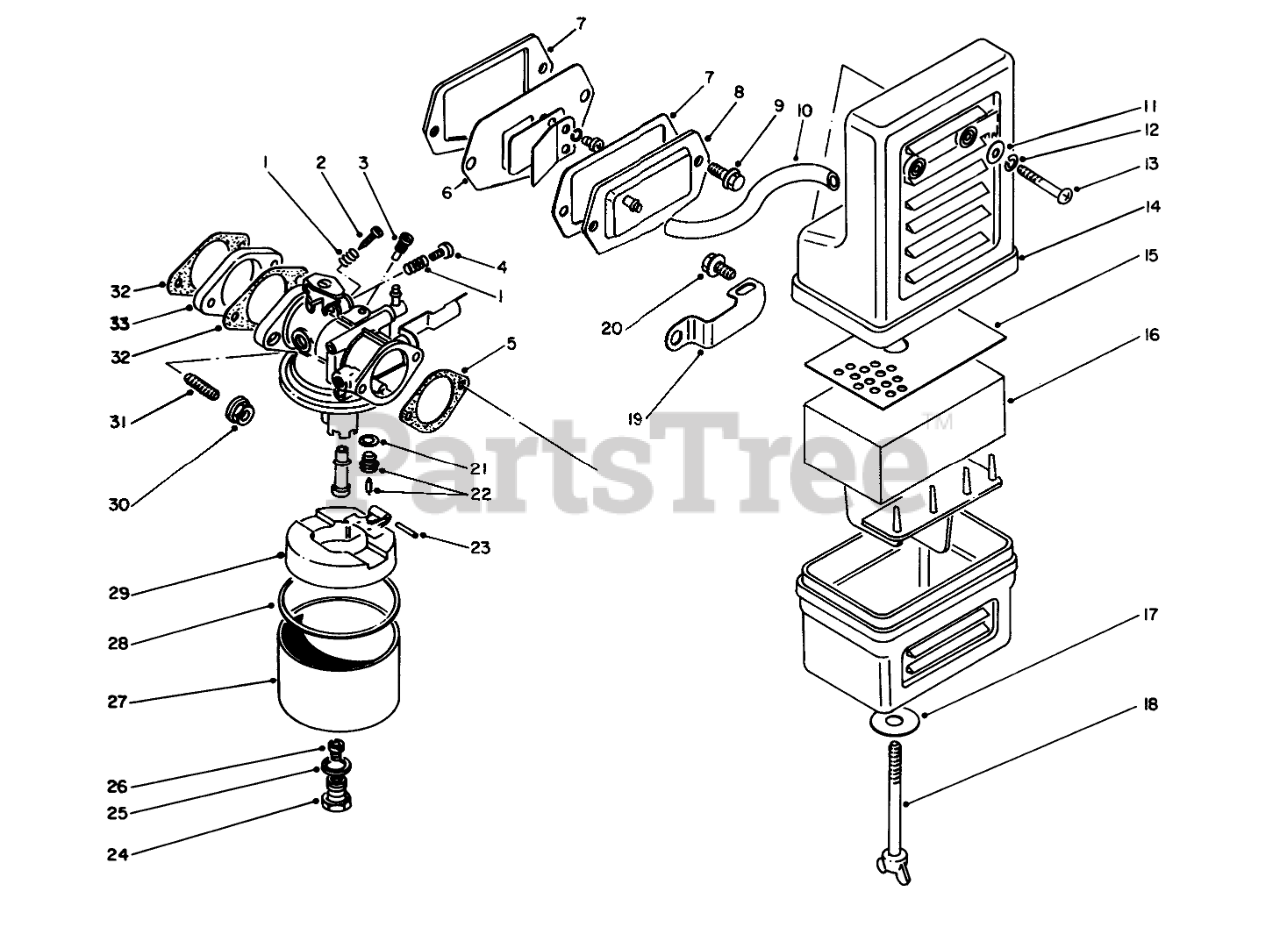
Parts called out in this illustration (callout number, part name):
1	SPRING-PILOT SCREW
2	ADJUSTER
3	Jet
4	SCREW
5	AIR CLEANER GASKET
6	Reed Valve Assembly
7	GASKET
11	WASHER
12	Washer
13	SCREW
14	Air Cleaner Assembly (Incl. Ref. #15-18)
15	Holder
16	FILTER
17	WASHER
18	Bolt-Wing
19	Bracket
21	GASKET
22	NEEDLE VALVE
25	GASKET
26	MAIN JET
27	Carburetor Assembly (Incl.Ref. #1-4, 21-26 & 28-29)
28	GASKET
29	FLOAT
31	Bolt-Stud
32	Gasket
33	INSULATOR
